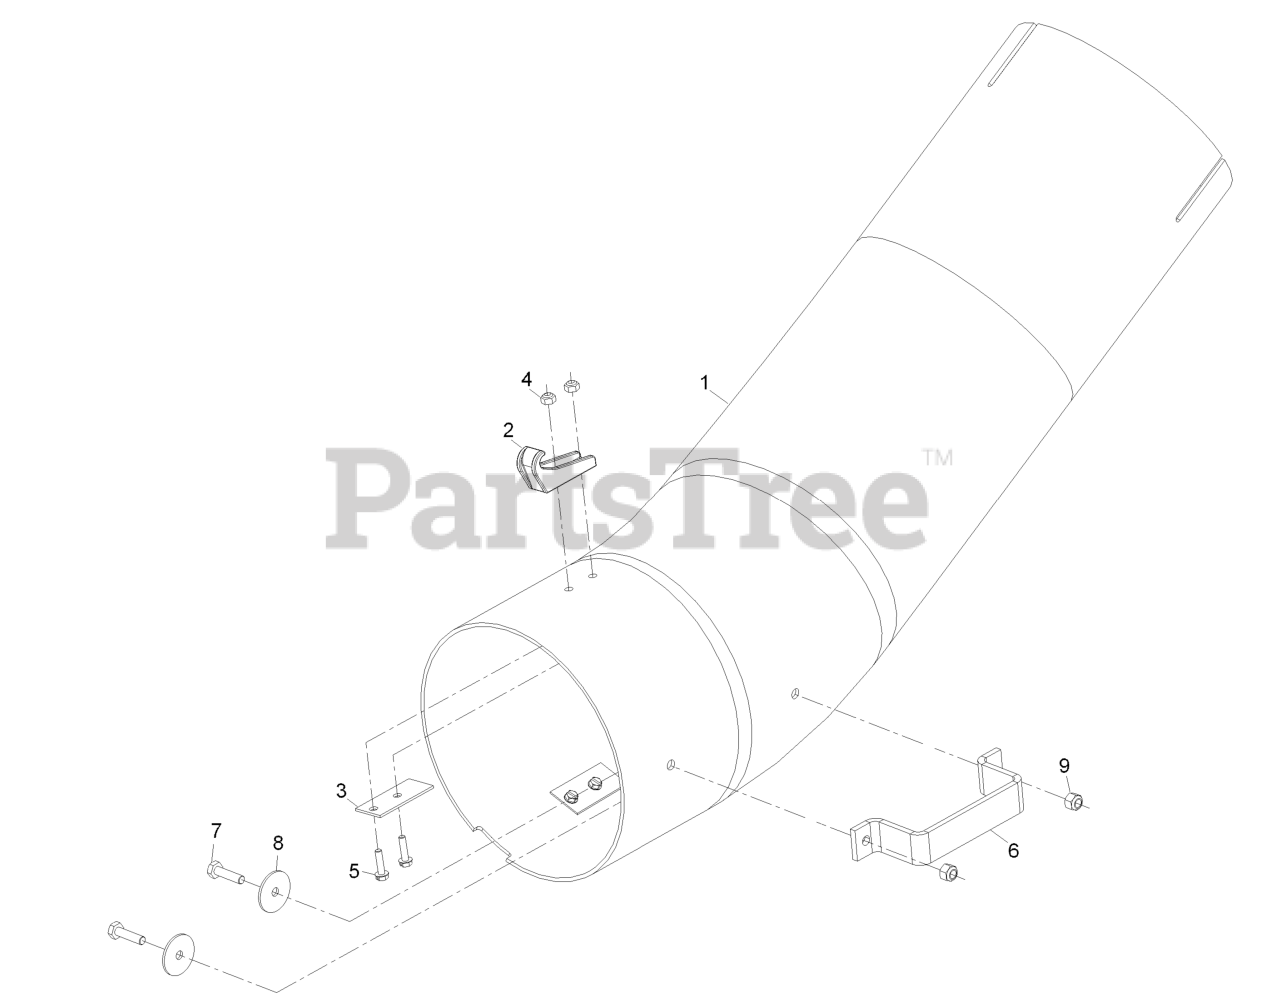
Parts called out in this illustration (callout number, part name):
1	TUBE-LOWER
2	LATCH-CATCH
3	PLATE-BACKING
4	NUT-LOCK, NI
5	SCREW-HWH
7	SCREW-HH
8	WASHER-FLAT
9	NUT-LOCK, NI
